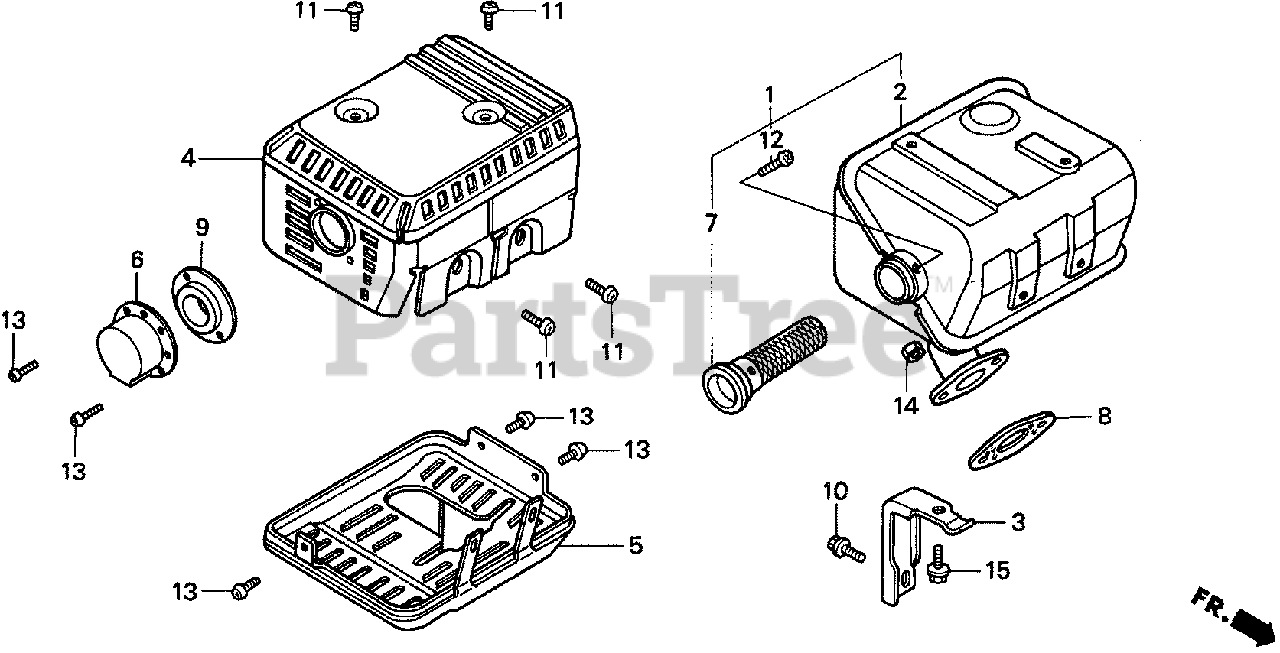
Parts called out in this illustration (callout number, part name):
2	MUFFLER
4	PROTECTOR, MUFFLER
6	DEFLECTOR
7	ARRESTER, SPARK
8	GASKET, MUFFLER
11	SCREW, TAPPING (5X8)
12	SCREW, TAPPING (4X6)
13	SCREW, TAPPING (4X6)
14	NUT, HEX. (8MM)
